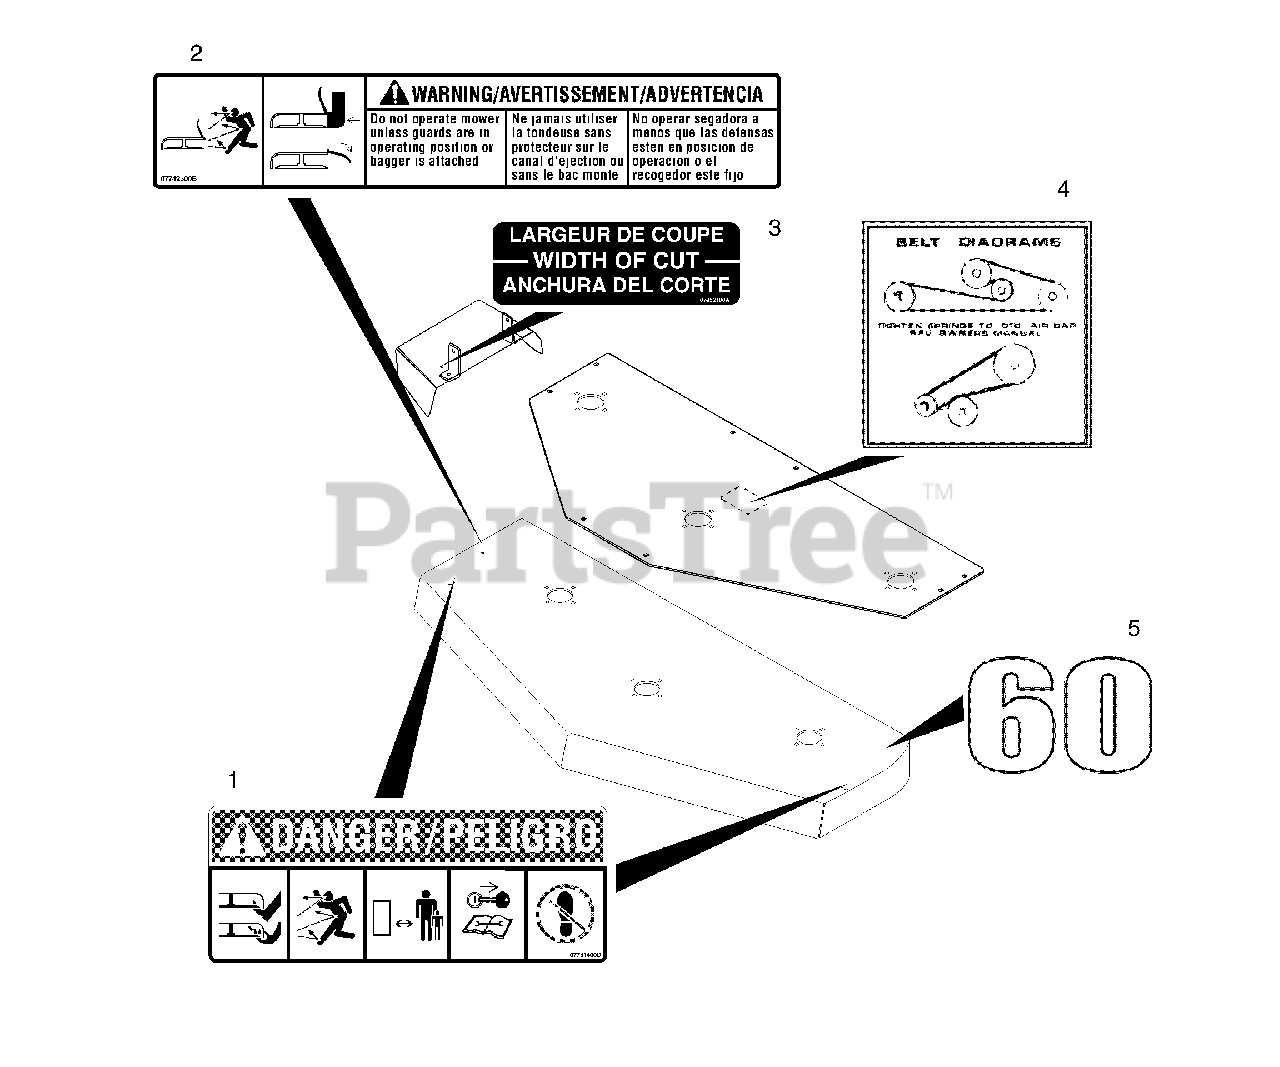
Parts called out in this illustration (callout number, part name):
1	Decal, Mower Pan Head Danger
2	Decal, Warning
3	Decal, Width of Cut
4	Decal-Belt Diagram
5	Decal, 60
